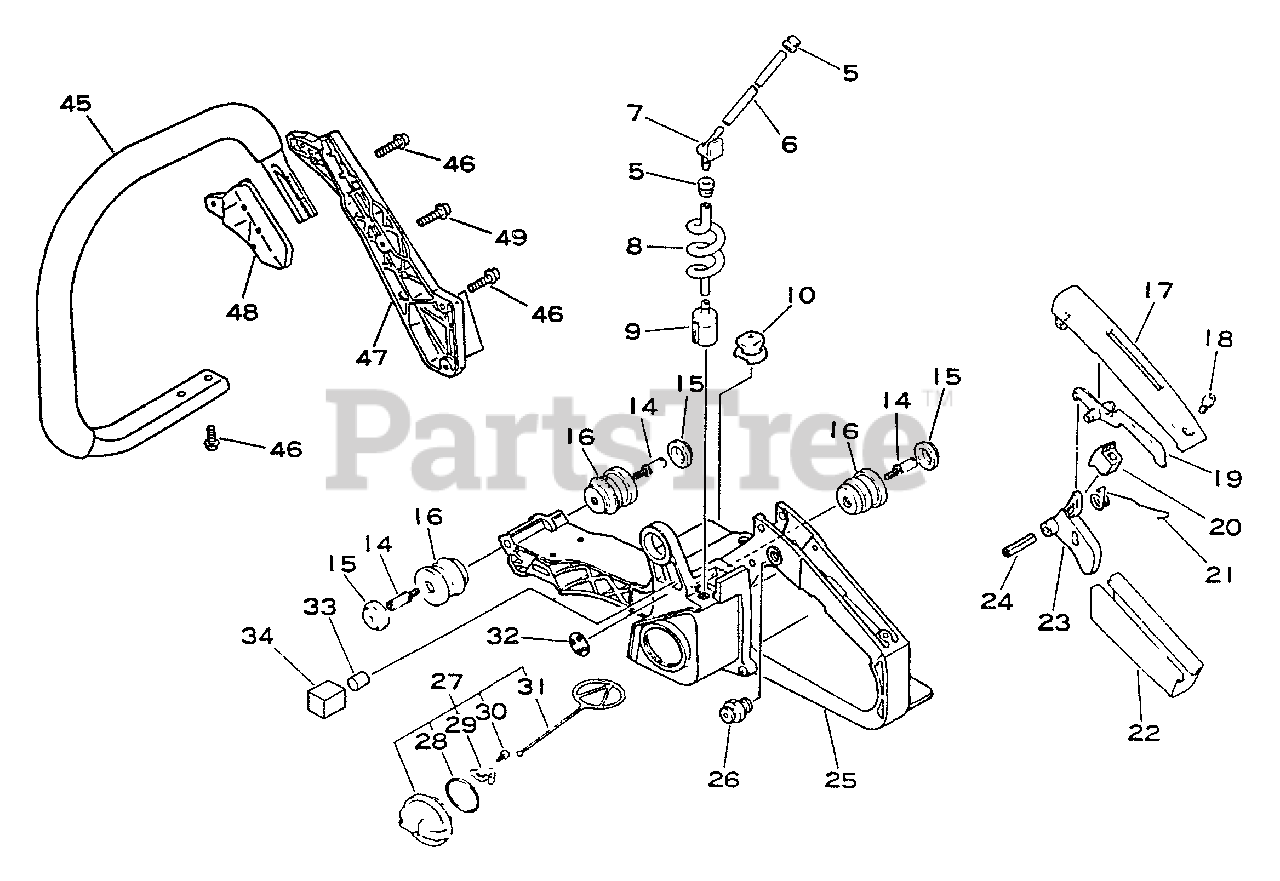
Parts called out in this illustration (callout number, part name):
5	GROMMET
6	PIPE - 3X6X100 -- BLACK
7	CONNECTOR, PIPE
8	PIPE, FUEL - SPIRAL
9	FILTER, FUEL
15	CAP, CUSHION
16	CUSHION
17	COVER, HANDLE
18	SCREW - 4X14
19	LOCKOUT, THROTTLE
21	SPRING, TRIGGER
22	GRIP, HANDLE
23	TRIGGER, THROTTLE
24	PIN - SPRING -- 5X25
25	HANDLE - REAR
26	LOCK, THROTTLE
27	CAP ASSY
28	O-RING - 29
29	RETAINER
30	SCREW - 3X8
31	CONNECTOR, CAP
33	COVER, VENT
34	FILTER
45	HANDLE - FRONT
46	SCREW - 5X20
47	BRACKET, HANDLE - OUTER
48	BRACKET, HANDLE - INNER
49	SCREW - 5X14
